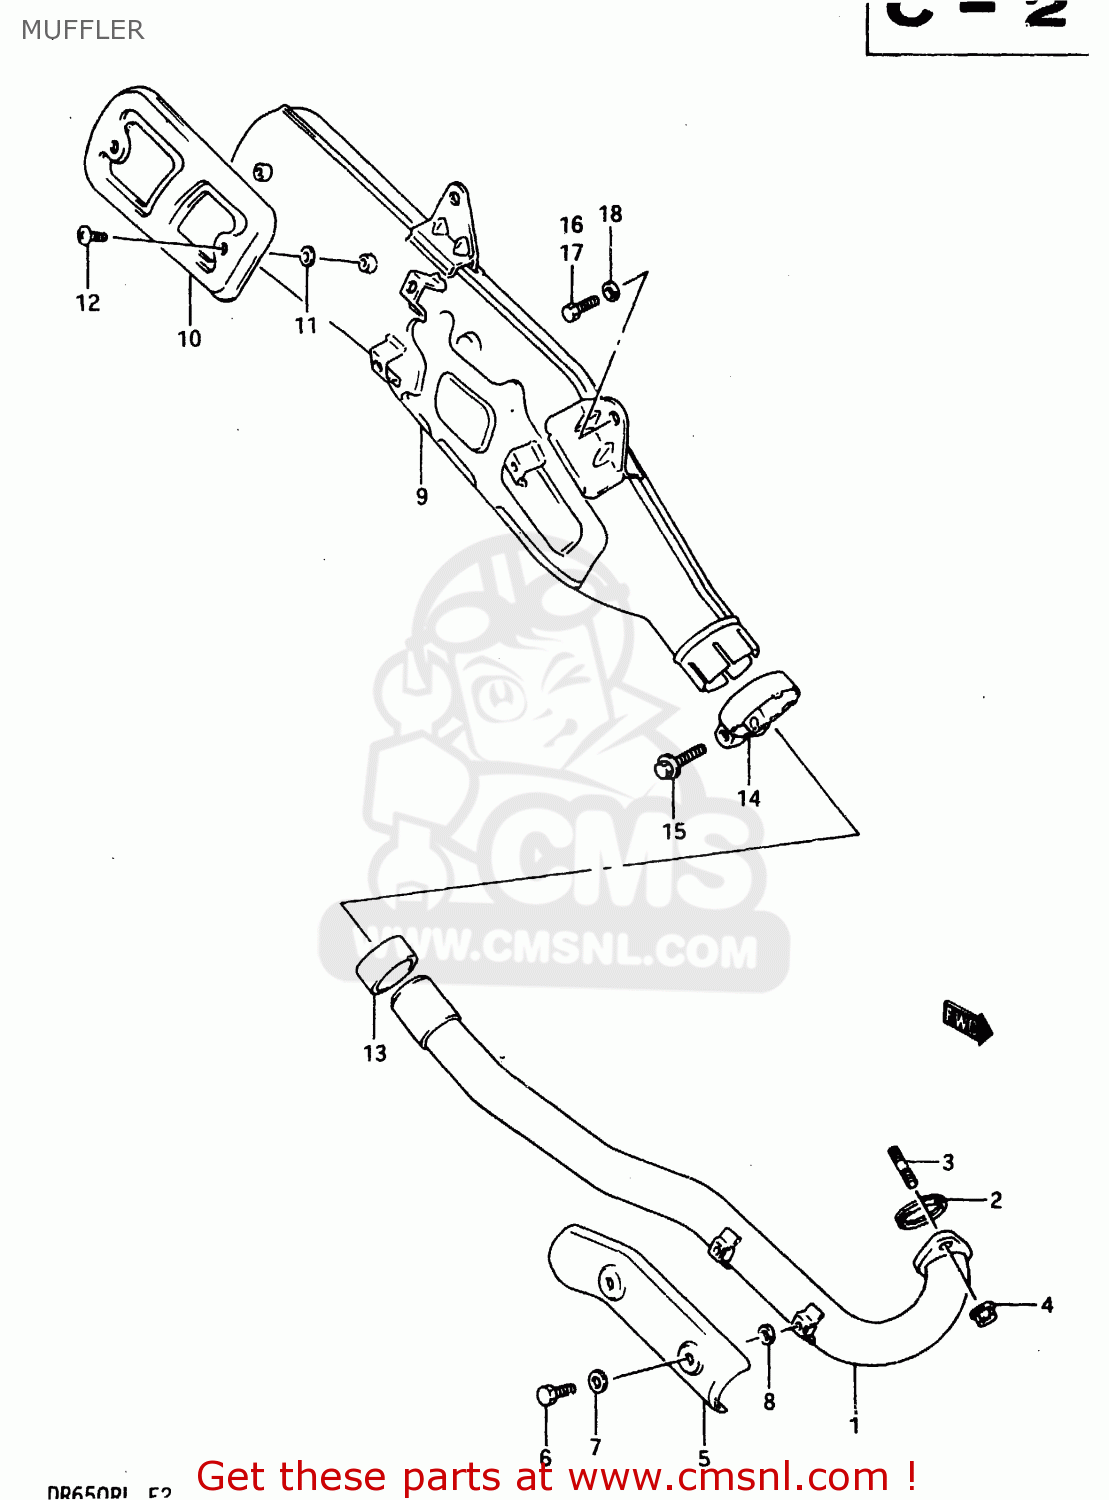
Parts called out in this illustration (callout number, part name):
1	PIPE,EXHAUST
2	GASKET,EXHAUST PIPE (NAS)
3	STUD BOLT
4	NUT
5	COVER,EXHAUST PIPE
6	SCREW
7	WASHER(6.5X18X1)
8	GASKET(6X16X1.4) (NAS)
9	BODY,MUFFLER
10	COVER,MUFFLER
11	GASKET,EXHAUST PIPE
12	SCREW
13	CONNECTOR,MUFFLER
14	CLAMP,MUFFLER CONNECTOR LH
15	BOLT 8X40
16	BOLT(8X20)
17	BOLT(8X20)
18	WASHER (8.5X19X2.3)
